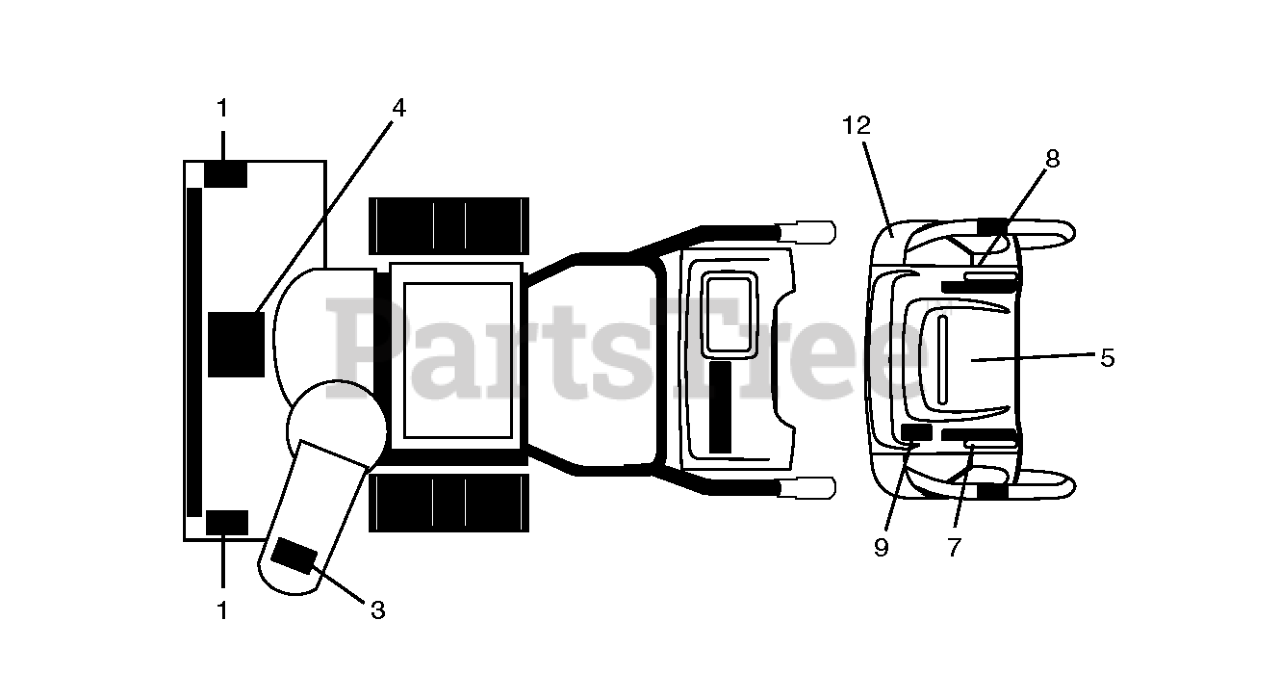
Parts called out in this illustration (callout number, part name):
1	DECAL.SNOWTHR.AUGER
3	DECAL.SNOWTHR.CHUTE.SAFETY
4	DECAL.SNOWTR.READ.OWN.MAN.E/F
5	DECAL.CONSOLE.SNOW.INST.ENG/FR
7	DECAL,LHTRIGGER
8	DECAL.CONS.RT.SPD/LEV/PWRST.
9	DECAL,HEIGHTADJUST
12	DECAL.CONSOLE.HAND.WARMER
